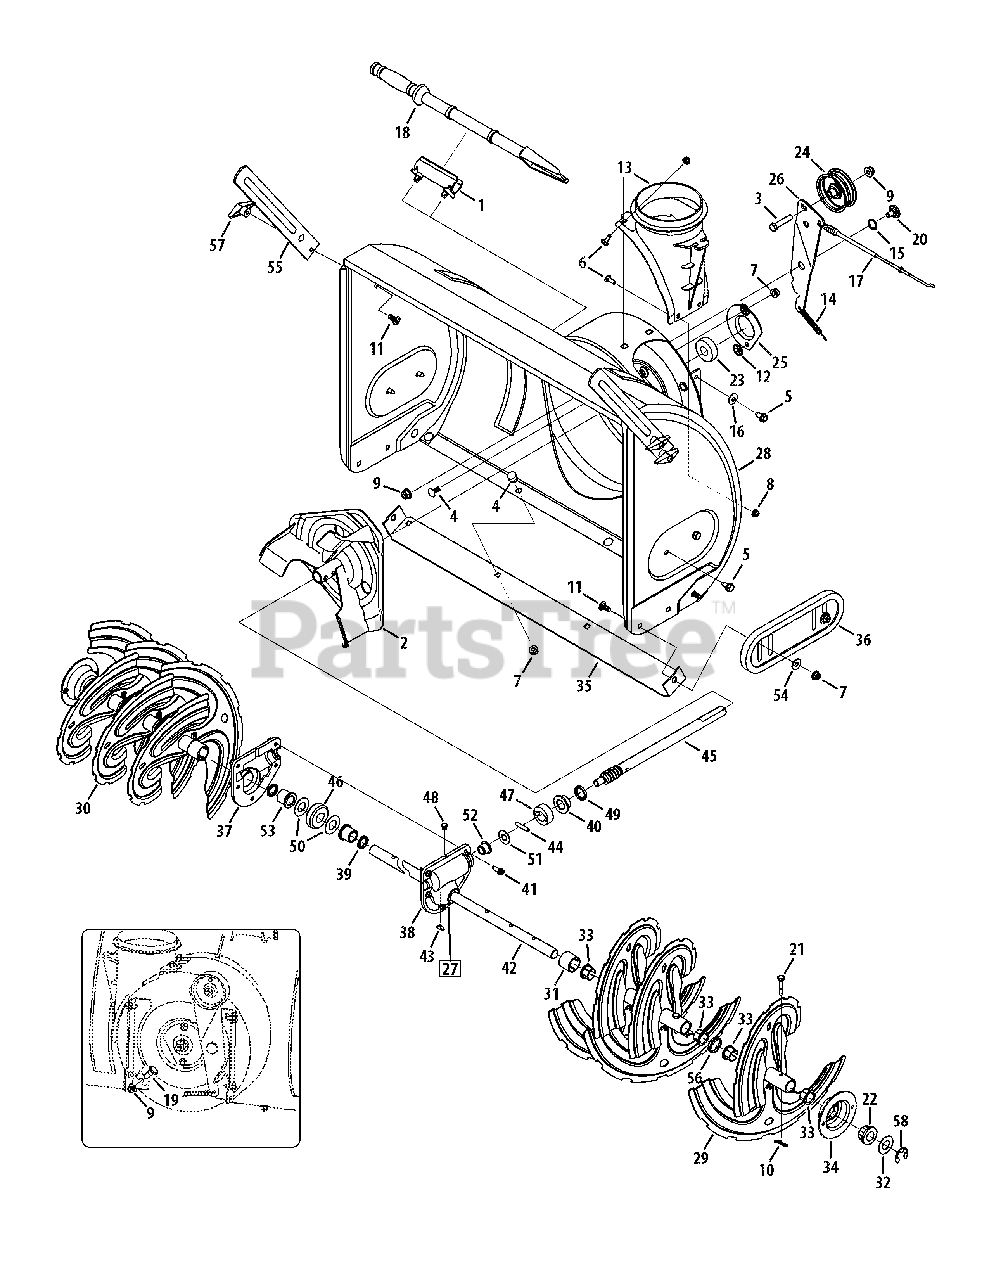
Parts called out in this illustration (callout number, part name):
1	Snow Removal Tool Mount
2	Impeller Assembly, 12" Dia.
3	Hex Screw, 3/8-16, 1.75, Gr5
4	Bolt, Carriage, 5/16-18, .750 Gr1
5	Screw, 5/16-18, 0.750
6	Screw, Carriage, 1/4-20, .750, Gr5
7	Nut, Flange Lock, 5/16-18, Nylon
8	Nut, Flange Lock, 1/4-20, Nylon
9	Nut, Flange Lock, 3/8-16, Nylon
10	Cotter Pin, Bow-tie
11	Scr., Crg., 5/16-18 x 1.00
12	Nut, Push-on, .25 Dia
13	Chute, Adapter 5" Dia
14	Spring, Extension, .38 OD x 4.59
15	Washer, Wave, .625 x .885 x .015
16	Washer, Bell, .340 x .872 x .060
17	Clutch Cable, Auger, 47.23"
18	Snow Removal Tool
19	Screw, Shoulder, .498 x .34, 3/8-16
20	Screw, Shoulder, .625 x .17, 3/8-16
21	Shear Pin, .25 x 1.50
22	Bearing, Hex Flange x .75 ID
23	Bearing, Ball, .75 ID x 1.85 OD
24	Flat Pulley, Idler, 2.75 OD
25	Housing, Bearing, 1.85 ID
26	Bracket, Auger Idler w/ Brake
27	Gearbox Assembly, Auger, 30"
28	Housing Assembly, Auger 30"
29	Spiral Assembly, LH
30	Spiral Assembly, RH
31	Spacer, 1.25 OD x .75 ID x 1.00
32	Washer, Flat, .76 x 1.49 x .06
33	Bushing, Flange, .80 ID x .91 OD
35	Shave Plate, 2.25 x 29.66
36	Slide Shoe
37	Housing, Auger, RH Reduced
38	Housing, Auger, LH Reduced
39	Seal, Oil, .750 x 1.00 x .125
40	Bearing, Flange, .75 x 1.0 x .59
41	Screw, Self-tapping, 1/4-20, 0.750
42	Axle, Auger, 30"
43	Key, Hi-pro 3/16 x 5/8
44	Pin, Dowel, .25 OD x 1.2
45	Shaft, Worm .75 OD
46	Gear, Worm 20T
47	Collar, Thrust
48	Plug, 1/4 x .437
49	Seal, Oil, .75 x 1 x .131
50	Washer, Flat, .760 ID x 1.5 OD
51	Washer, Flat, .51 x 1.12
52	Bearing, Flange, .75 x 1.0 x .925
53	Bearing, Flange, .75 x 1.00 x .975
54	Washer, Flat, .349 x .879 x .063
55	Drift Cutter
56	Spacer, 1.25 OD x .75 ID x 3/16
57	Wing Nut
58	E-Ring
